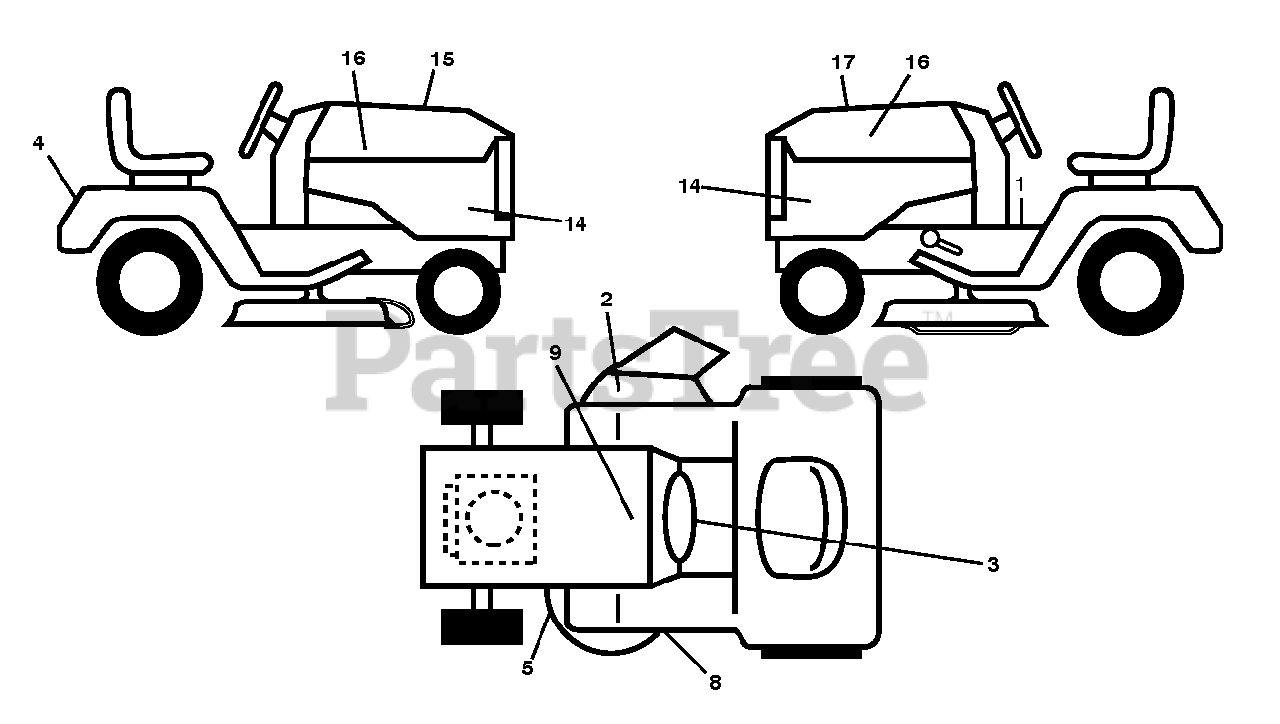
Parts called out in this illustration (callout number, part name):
1	DECAL.WARN.STARTINST.LOWEARIEN
2	DECAL.MOWER.WARN.KEEP.HAND.AWY
3	DECAL, WARNING SPARK ARRESTOR
4	DECAL.FENDER
5	DECAL.MOWER.CAUTION.TENSION.AR
8	DECAL.MOWER.SCH.48/54.PREM
9	DECAL BTRY SYMBOLS
14	DECAL.SIDE.PANEL.YTH24K48
15	DECAL.WARNING.CUST.RESP.E85.
16	DECAL.BADGE.170MM.TEXTLOGO.
